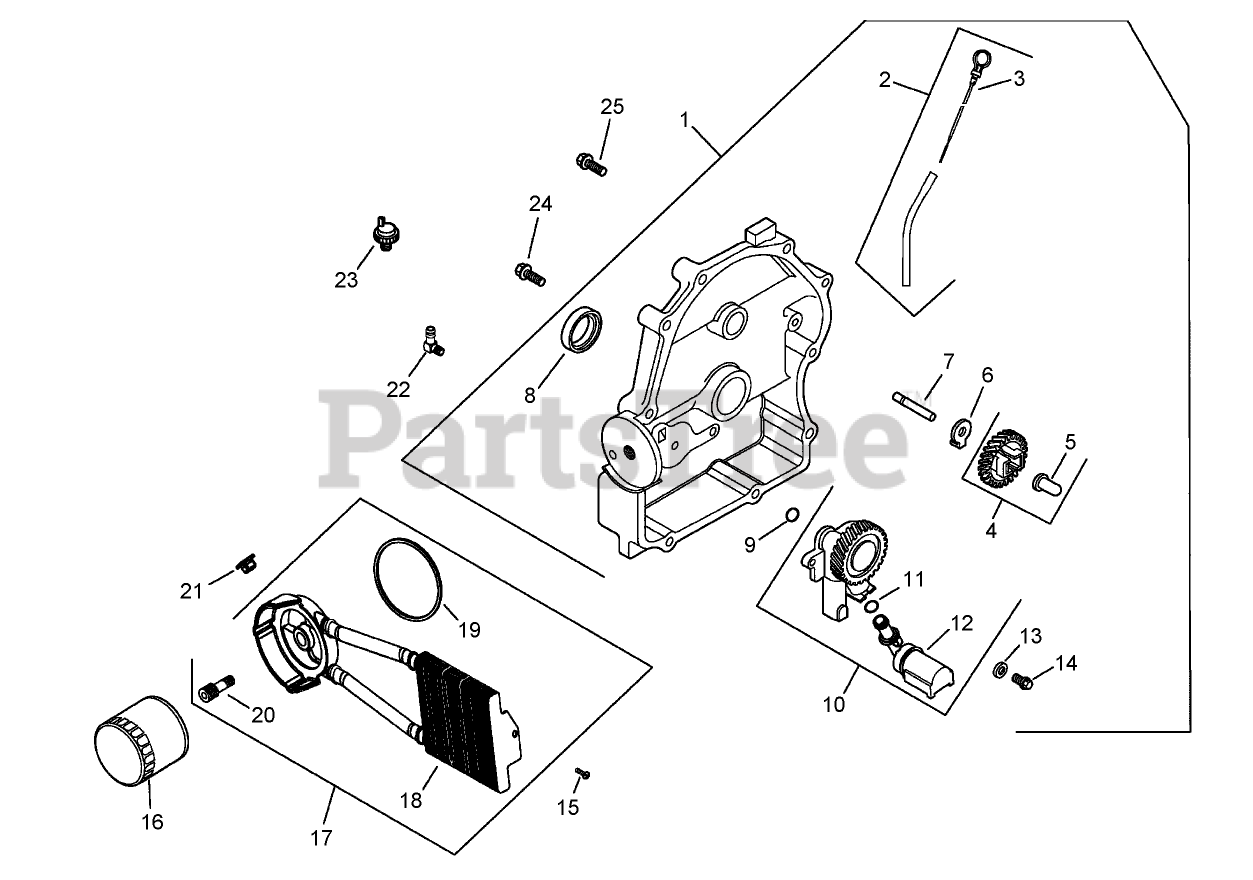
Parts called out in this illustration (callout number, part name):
1	Closure Plate ASM (Includes 2-14)
2	Dipstick Tube ASM (Includes 3)
3	Dipstick
4	Governor Gear Kit (Includes 5)
5	PIN-REGULATING, GOVERNOR
6	TAB-LOCKING
7	SHAFT-GEAR, GOVERNOR
8	SEAL-OIL (P-T-O END)
9	O-Ring
10	Oil Pump ASM (Includes 11,12)
11	TUBE-PICK UP, OIL
12	O-RING
13	WASHER-FLAT (6 MM)
14	SCREW-FLANGE, THREAD FORMING (M6X1.0X25)
15	SCREW-TAPPING
16	FILTER-OIL
17	Oil Cooler Kit (Includes 18-20)
18	Cooler-Oil (Phenolic)
19	O-RING
20	Nipple-Filter, Oil
21	Nut-Plastic
22	Connector-Hose, 90 Deg
23	SWITCH-PRESSURE, OIL
24	Screw-HF (M8x1.25x45)
25	SCREW-FLANGE (M8X1.25X45)
